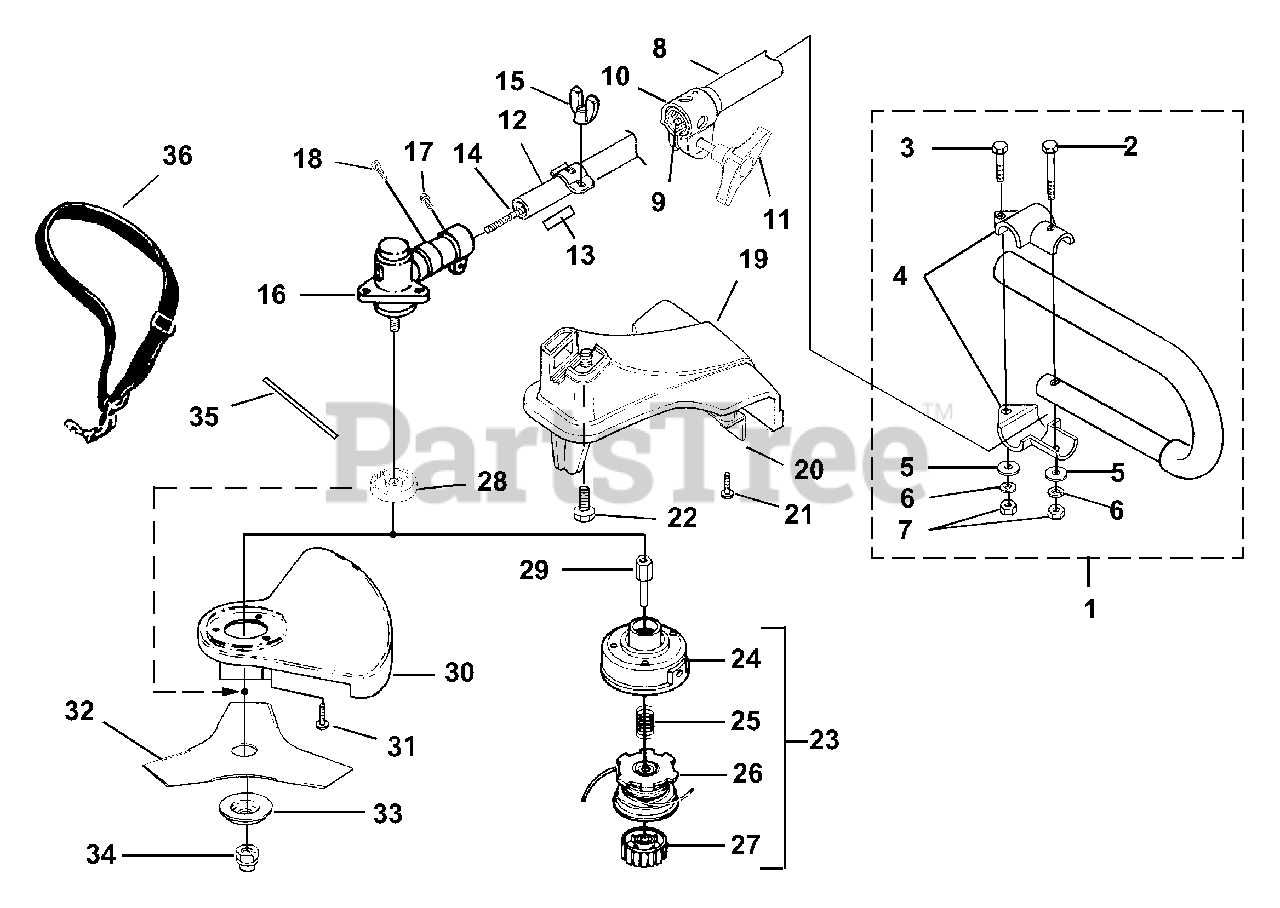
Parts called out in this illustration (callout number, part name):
1	HANDLE ("J")
2	SCREW-Hex Hd. (1/4-20 X 1 1/2")
3	SCREW-Hex Hd. (1/4-20 X 1")
4	CLAMP-Handle Bar
5	WASHER-Flat (1/4")
6	WASHER-Lock (1/4")
7	NUT-Hex (1/4-20)
8	DRIVESHAFT HOUSING (Upper)
9	FLEXSHAFT-w/Collar & Liner
10	COUPLER KIT
11	KNOB
12	DRIVESHAFT HOUSING (Lower)
13	DECAL-Warning
14	SHAFT-Flexible
15	WING NUT
16	GEAR HEAD
17	Screw, Cap Hd. (1/4-20 X 7/8")
18	Screw-Hex Hd. (10-24 x 1/2")
19	GRASS DEFLECTOR KIT
20	BLADE-Cut-Off
21	SCREW, Thread Form. (10-24 X 3/4")
22	SCREW-Square Head
23	STRINGHEAD-Complete (.095")
24	HOUSING & EYELET (Dual Line)
25	SPRING-Compression
26	SPOOL & STRING (.095")
27	RETAINER-Spool (L.H. Thread, Red)
28	WASHER-Flanged
29	ADAPTER-Shaft
30	BLADE GUARD
31	SCREW
32	BLADE-Tri-Arc(TM)
33	WASHER-Cupped (Lower)
34	NUT-Hex (L.H.)
35	TOOL-Holding Pin
36	HARNESS
